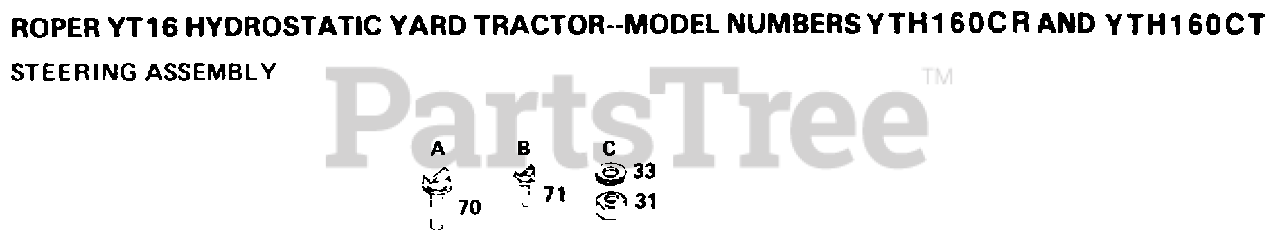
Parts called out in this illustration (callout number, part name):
33	WASHER
70	SCREW
71	SCREW LT
